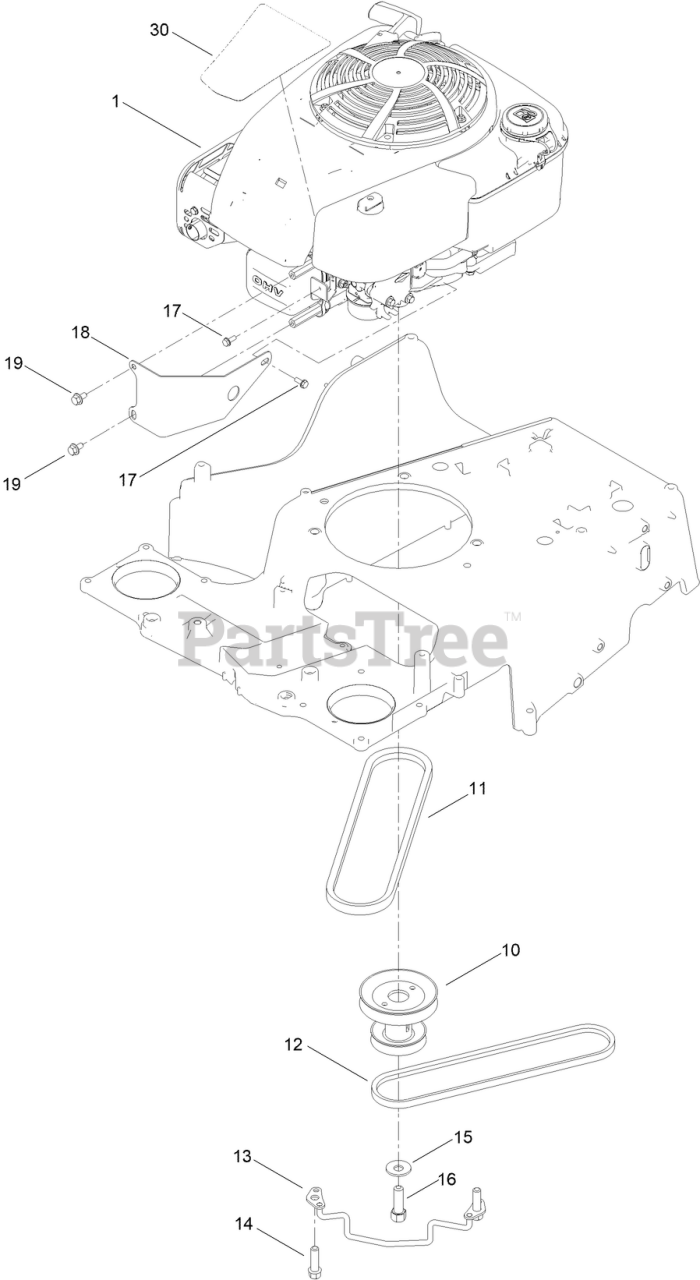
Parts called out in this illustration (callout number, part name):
10	PULLEY-ENGINE
11	V-BELT
12	V-BELT, TRACTION
13	GUIDE-BELT, WA
14	SCREW-TAPTITE
15	WASHER-BELLEVILLE
16	SCREW-HH
17	SCREW-TAPTITE
18	GUARD-ENGINE
19	SCREW-HHF
30	DECAL-SHROUD
